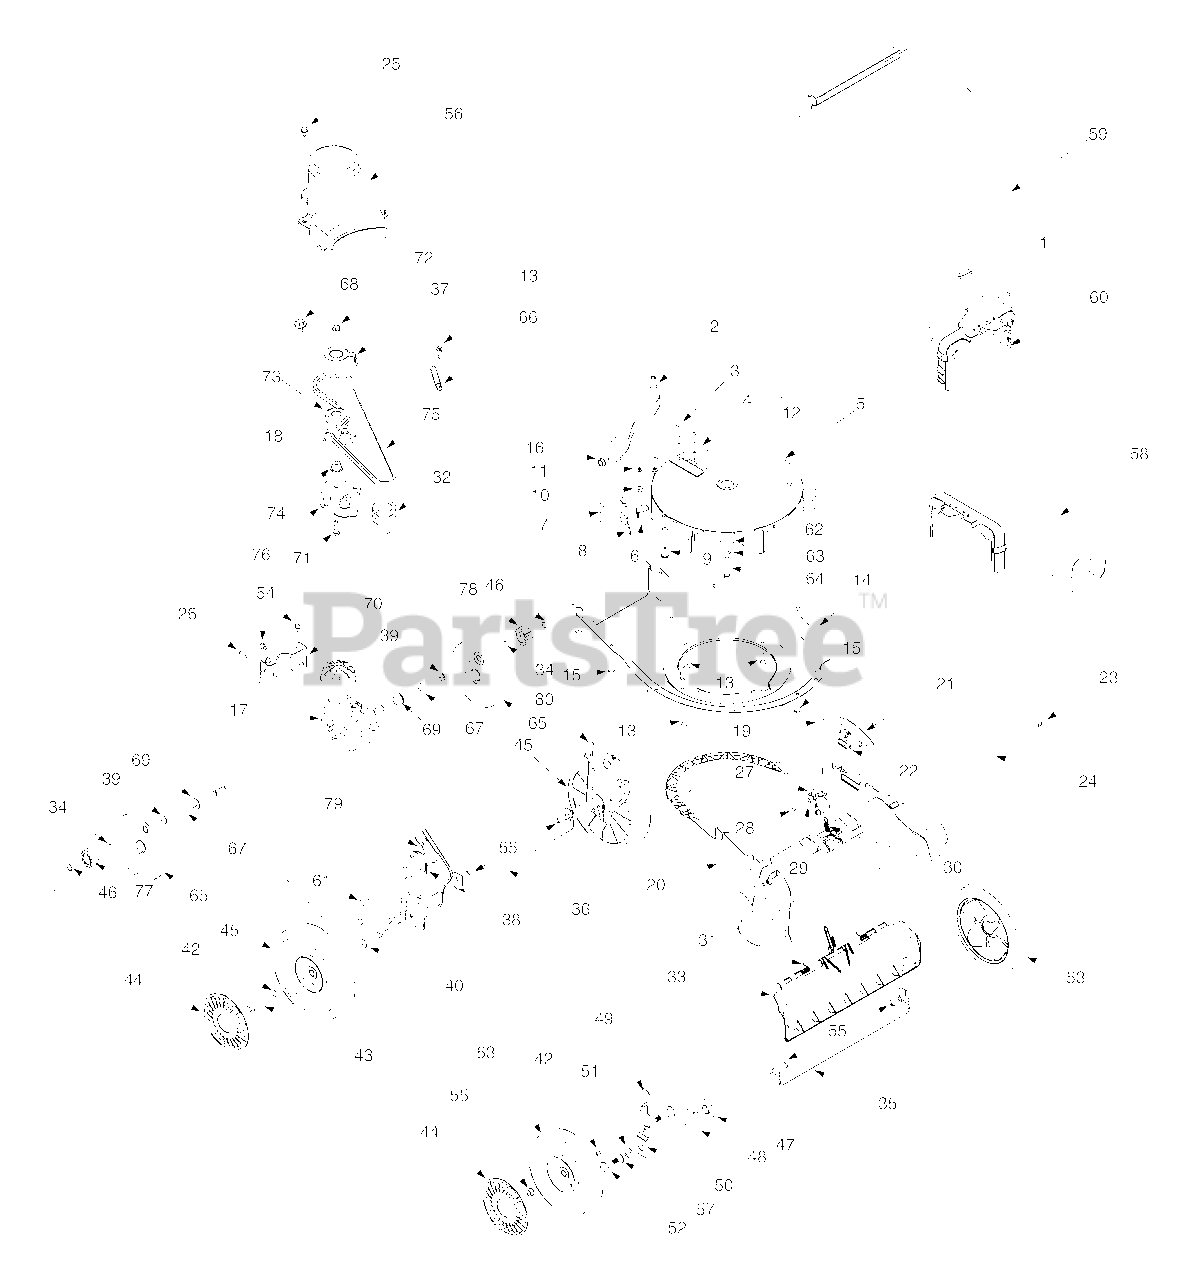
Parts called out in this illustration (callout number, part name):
1	Bag Assembly
3	Hex Screw 5/16-24 x 1.0
4	Chipper Blade
5	Impeller
6	Pin Clip
7	Flail
8	Spiral Pin
9	Clevis Pin
10	Lock Nut, 5/16-24
11	Lock Washer, 5/16
12	Impeller Assembly
13	Shoulder Screw, #12-24 x.30 x.46
15	Flange Lock Nut 5/16-18
16	Screw, 5/16-18 x.500
17	Transmission Assembly
18	Idler Assembly
19	Hinge Pin
20	Nozzle
21	Base Adapter Door
22	Torsion Spring
23	Cap Speed Nut 1/4
24	Pivot Rod
25	Screw, 1/4-20 x.500
26	Screw, #12-16 x.750
27	Nozzle Door Lever
28	Hex Screw, #8-18 x 1.25
29	Shoulder Spacer
30	Extension Spring
31	Nozzle Door Torsion Spring
32	Impeller Hub
33	Nozzle Door
34	Dowel Pin
37	Belt Keeper
38	Cotter Pin
39	E - Ring
40	Flat Washer,.385 x 1.00 x.135
42	Wave Washer.531 ID x.781 OD
43	Shoulder Screw 3/8-16
44	Hubcap
45	Wheel 8 x 2.125
46	Snap Ring
47	Height Adjustment Bearing
48	Pivot Arm Assembly
49	Height Adjustment Knob
50	Spring Lever
51	Bell Washer.760 ID x.25 OD
52	Shoulder Screw,.750 x.500
53	Wheel 8 x 2.125
54	Screw, 1/4-20 x.625
55	Flange Lock Nut, 3/8-16
56	Belt Cover
57	Thrust Washer.375 ID x.70 OD
58	Blower Chute
59	Bag
60	Chute Assembly
61	Hex Index Screw, 5/16-12 x.750
62	Flat Washer.375 ID x 1.25 OD
63	Lock Washer 3/8
64	Hex Cap Screw 3/8-24 x 2.75
65	Wheel Cover
66	Extension Spring,.375 x 2.95
67	Flat Washer,.508ID x1.00OD x.020
68	Shoulder Screw,.560 x.165
69	Drive Axle Bushing
71	Screw, 1/4-20 x 1.00
72	Flange Lock Nut, 1/4-20
73	Ball Bearing
74	Flange Spacer,.260 x.659 x.517
75	Belt, 3/8 x 32.5
77	Spur Gear - RH
78	Spur Gear - LH
